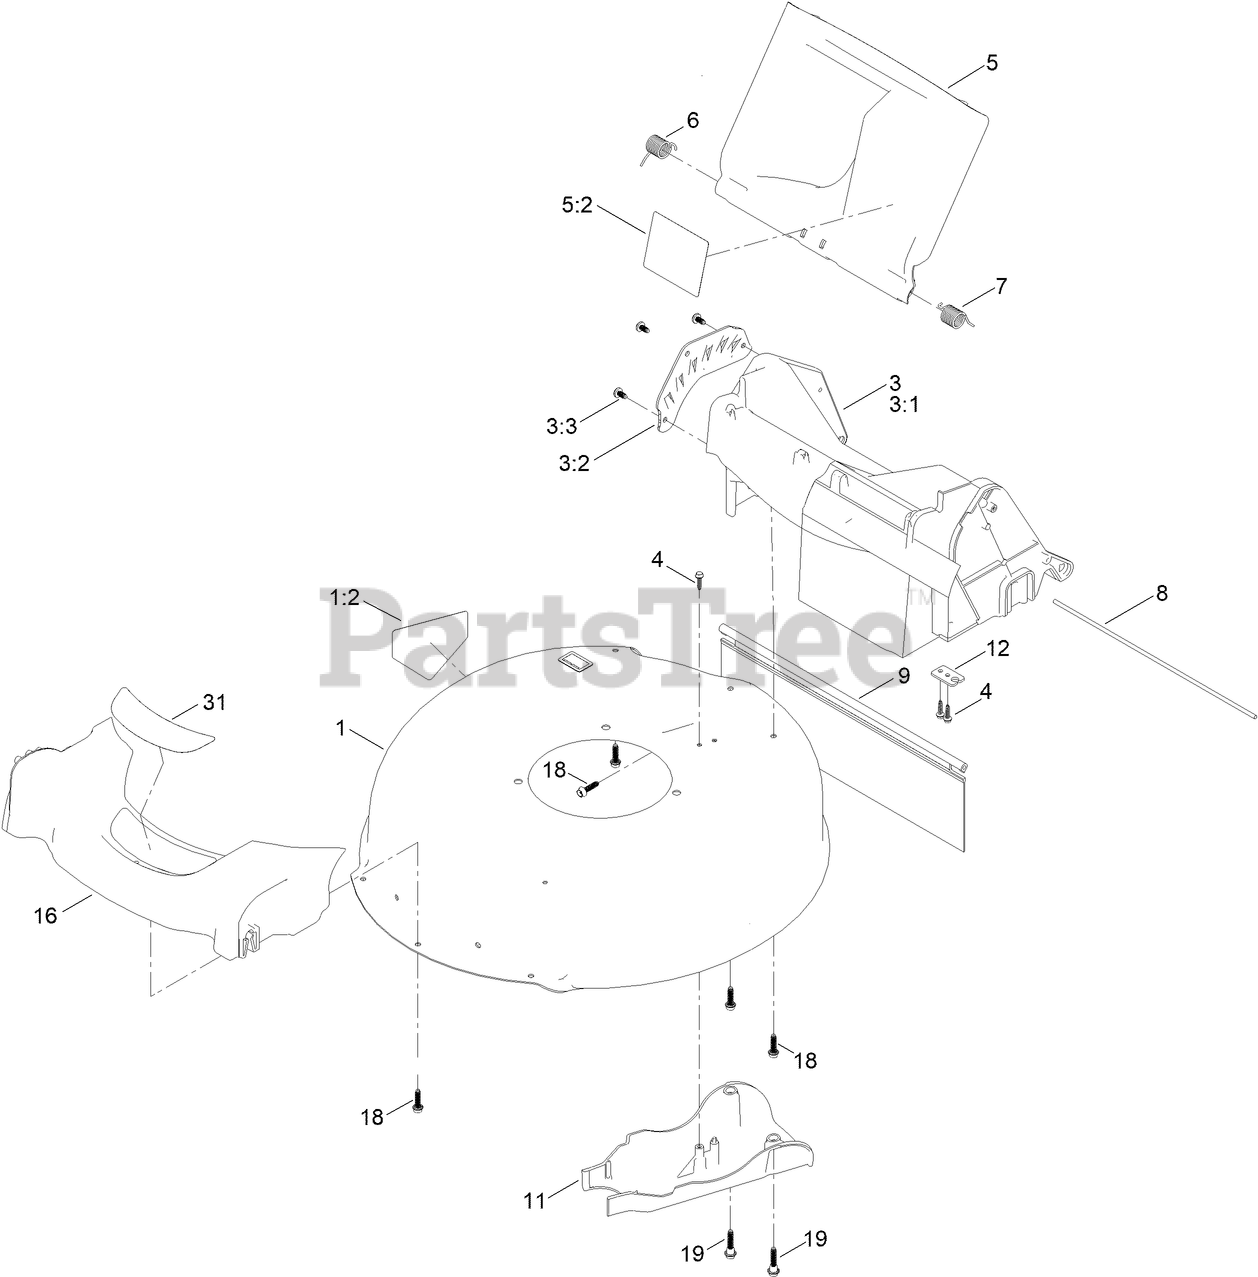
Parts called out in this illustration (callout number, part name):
1	HOUSING ASM
1:2	DECAL-DANGER
3	CHUTE ASM
3:1	CHUTE-SP/AWD, 21 IN
3:2	PLATE-HOC
3:3	SCREW-PLASTIC,PH
4	SCREW-HWH
5	REAR DEFLECTOR ASM
5:2	DECAL-WARNING
6	SPRING-TORSION
7	SPRING-TORSION
8	ROD-DOOR
9	SHIELD-TRAILING
11	COVER-BELT
12	BRACKET-CABLE
16	BUMPER
18	SCREW-FLANGE, PLASTIC
19	SCREW-SHOULDER, HHF
31	DECAL-DECK
